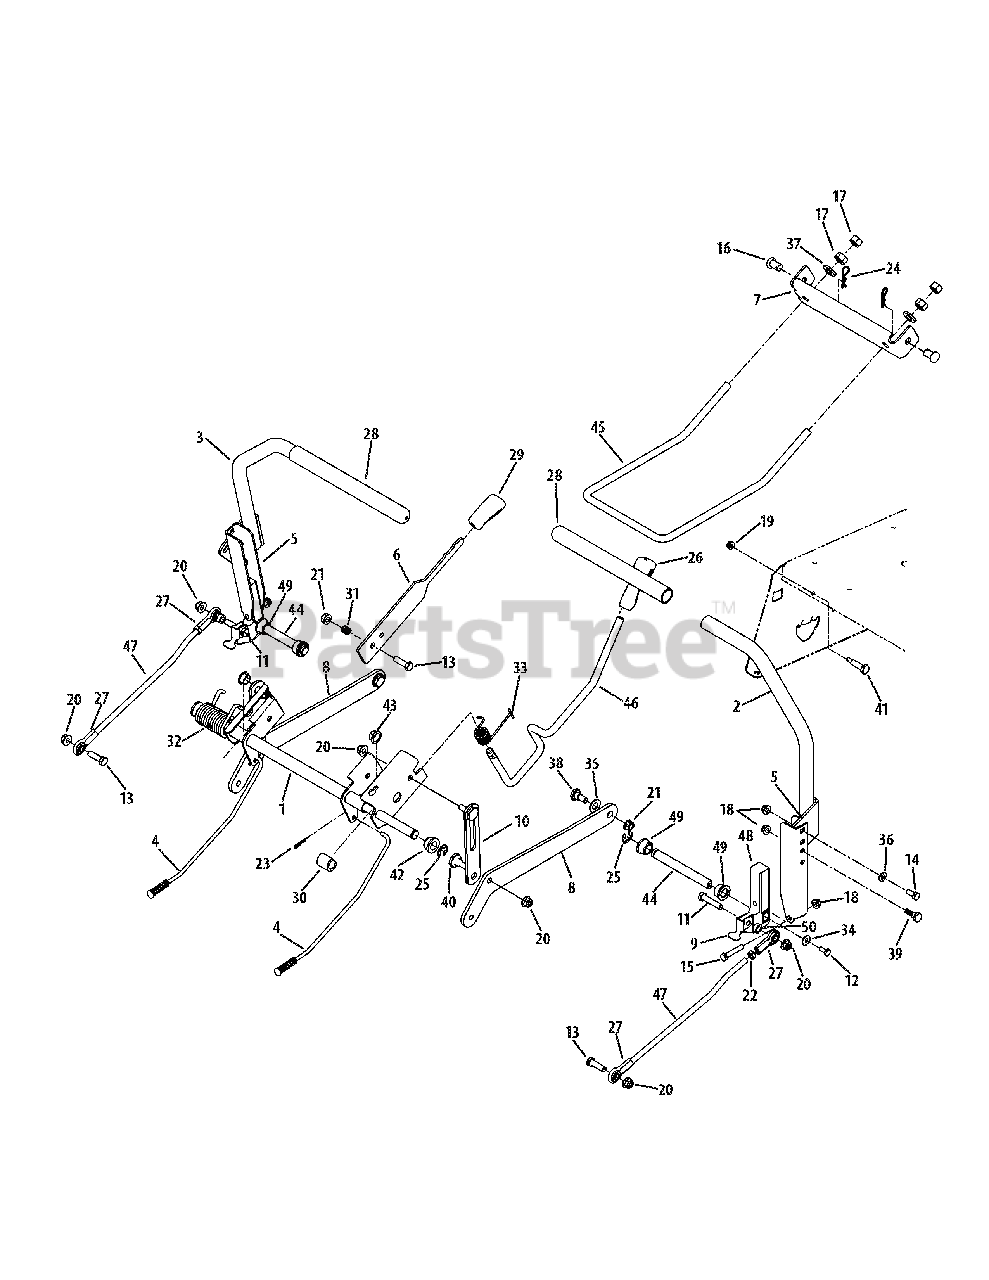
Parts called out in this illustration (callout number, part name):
2	RH Lapbar Lever Assembly
3	LH Lapbar Lever Assembly
4	Brake Rod Assembly
5	Lapbar Pivot Bracket
6	Brake/Shabs Handle
7	Front Deck Hanger Bracket
8	Deck Lift Arm Plate
9	Switch Actuator Bracket
10	Lift Link Plate
11	Hex Screw, 3.8-16 x 1.75
12	Hex Screw, 1.4-20 x .625
13	Hex Screw, 3.8-16 x 1.25
14	Hex Screw, 5.16-18 x .75
15	Hex Screw, 5.16-18 x 1.75
16	Clevis Pin, .50 x .78
17	Hex Nut, 1.2-13
18	Flange Lock Nut, 5.16-18
19	Flange Lock Nut, 1.4-20
20	Flange Lock Nut, 3.8-16
21	Flange Lock Nut, 3.8-16
22	Jam Nut, 3.8-24
23	Cotter Pin, .072 x 1.13
24	Cotter Pin, .080 x 1.5625
26	Handle Grip
28	Lapbar Grip
29	Selector Handle
30	Spacer, .621 x 1.00
31	Compression Spring, .50 x .50
32	Torsion Spring, 1.19 x 2.78
33	Spring, Torsion RZT
34	Bell Washer, .265 x .75 x .062
35	Flat Washer, .510 x 1.00 x .060
36	Flat Washer, .344 x .688 x .065
37	Flat Washer, .531 x 1.062 x .134
38	Shoulder Bolt, 3.8-16 x .496 x .336
39	Shoulder Screw, 5.16-18 x .437 x .268
40	Shoulder Screw, .500 x .434
41	Shoulder Screw, .374 x 1.16
42	Hex Flange Bearing
43	Flange Bearing, .626 x .938 x .344
44	Shift Control
45	Front Hanger Deck Lift Rod
46	Deck Lift Handle Rod
47	Lapbar Rod Control
48	Control Hub
49	Hex Flange Bearing
50	Spacer, .380 x .625 x .265
